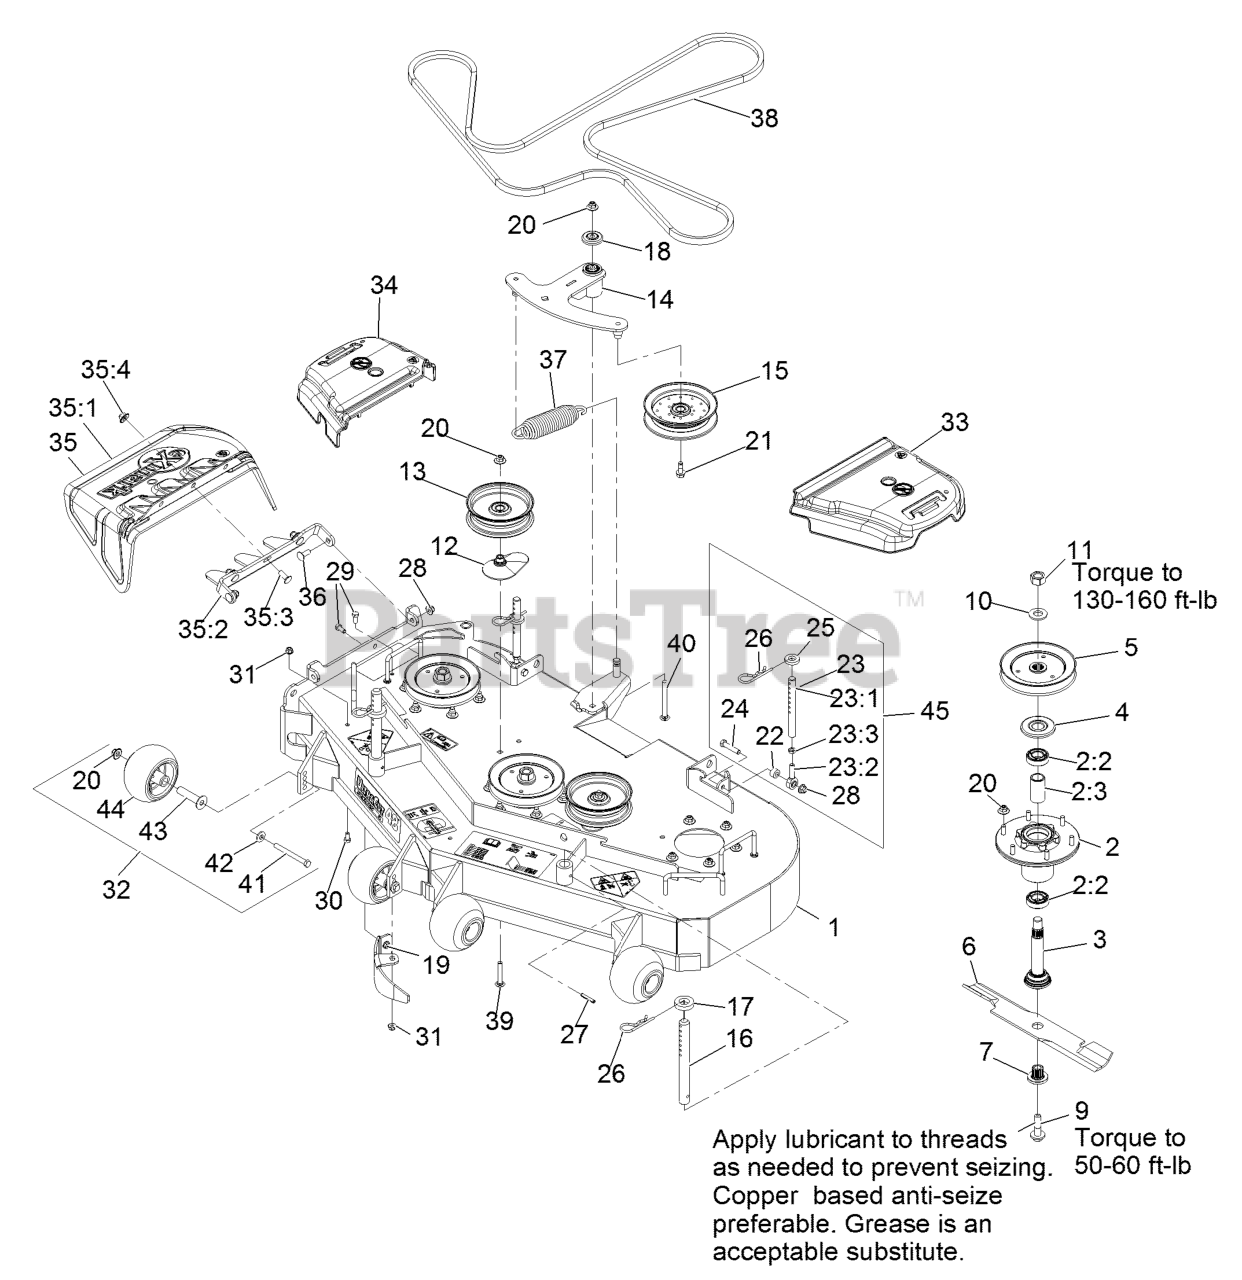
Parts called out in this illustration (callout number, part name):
1	ASM, DECK 48" W/DECALS
2	ASM-CUTTER HSG WITH BEARINGS
2:2	BEARING-BALL
2:3	SPACER-BEARING
3	ASM-SPINDLE AND SEAL
4	GUARD,BEARING TOP .989
5	SHEAVE,BLADE DRIVE 5.90
7	BUSHING,SPLINED
9	SCREW,SEMS 1/2-20 X 2.19
11	NUT-HEX
12	SPACER-PULLEY
13	IDLER-PULLEY, FLAT
14	ASM, DECK IDLER
16	ROD,DECK SUPPORT
17	SPACER-DECK SUPPORT
18	GUARD-TOP
19	BAFFLE, DOGLEG
20	Nut-Nyloc 3/8-16 Flg
21	SCREW-HFH
23:1	LINK,SUPPORT
23:2	BALLJOINT
23:3	NUT-HJ
24	SCREW-HH
26	PIN,HAIR COTTER
28	NUT-HF, NI
29	SCREW-HH
30	SCREW-HH
31	NUT-HF, NI
32	KIT, ANTI-SCALP ROLLER
33	COVER-BELT, LH
34	COVER-BELT, RH
35	ASM, DISCHARGE CHUTE
35:1	CHUTE,DISCHARGE
35:2	BRACKET, DISCHARGE CHUTE
35:3	SCREW-CARR
35:4	Nut-Nyloc 3/8-16 Flg
36	SCREW-CARR
37	SPRING-EXTENSION
38	BELT, DECK
39	BOLT-CARR, SHORT NECK
40	SCREW-CARR
41	SCREW-HH 3/8-16 X 3 3/4 GR 8
42	WASHER-BELLEVILLE
43	AXLE, ROLLER
44	ROLLER-SCALP, ANTI
45	KIT,SUPPORT LINK W/PIN
